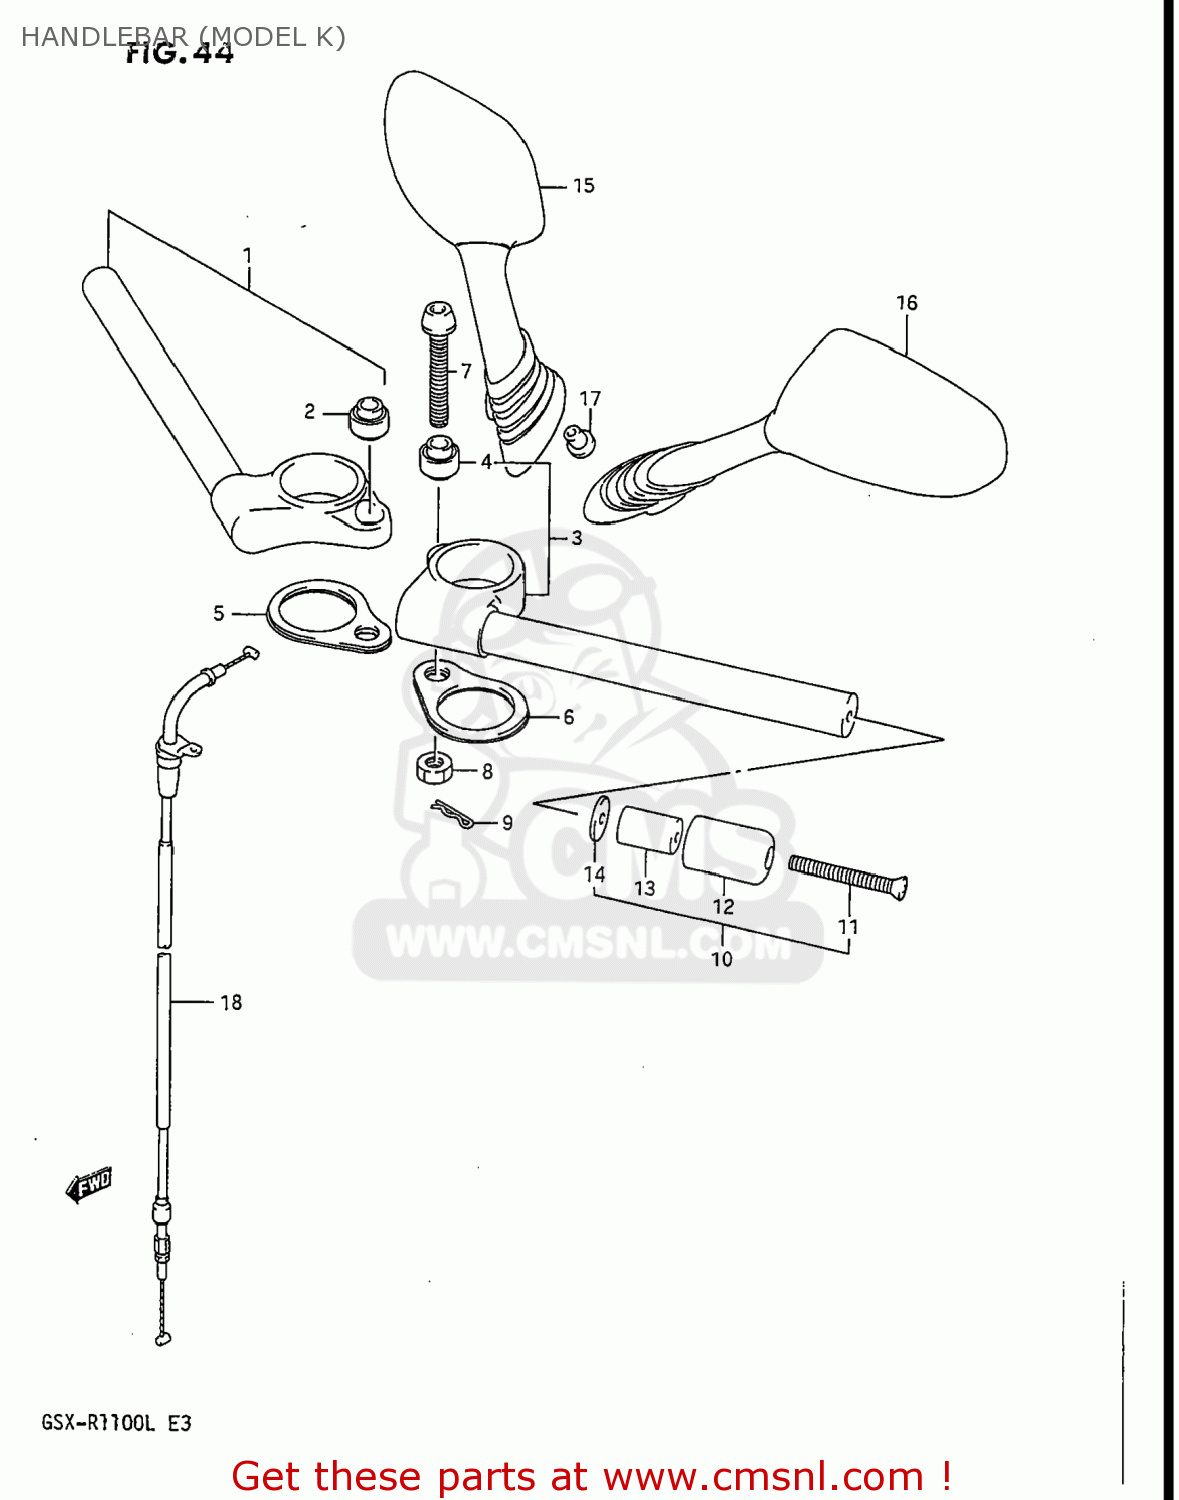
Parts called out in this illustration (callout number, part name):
1	HANDLEBAR,R
2	BUSH(10.2X20X15)
3	HANDLEBAR,LEFT
4	BUSH(10.2X20X15)
5	CUSHION,HANDLEBAR,R
6	CUSHION,HANDLEBAR,L
7	BOLT,HANDLE HOLDER
8	NUT
9	CLIP
10	BALANCER SET,HANDLEBAR
11	SCREW (L:65)(SUS)
12	CAP,BALANCER
13	BALANCER,HANDLEBAR
14	SPACER,BALANCER
15	MIRROR ASSY,RR VIEW,R
16	MIRROR ASSY,RR VIEW,L
17	NUT,RR VIEW MIRROR
18	CABLE ASSY,THROTTLE
